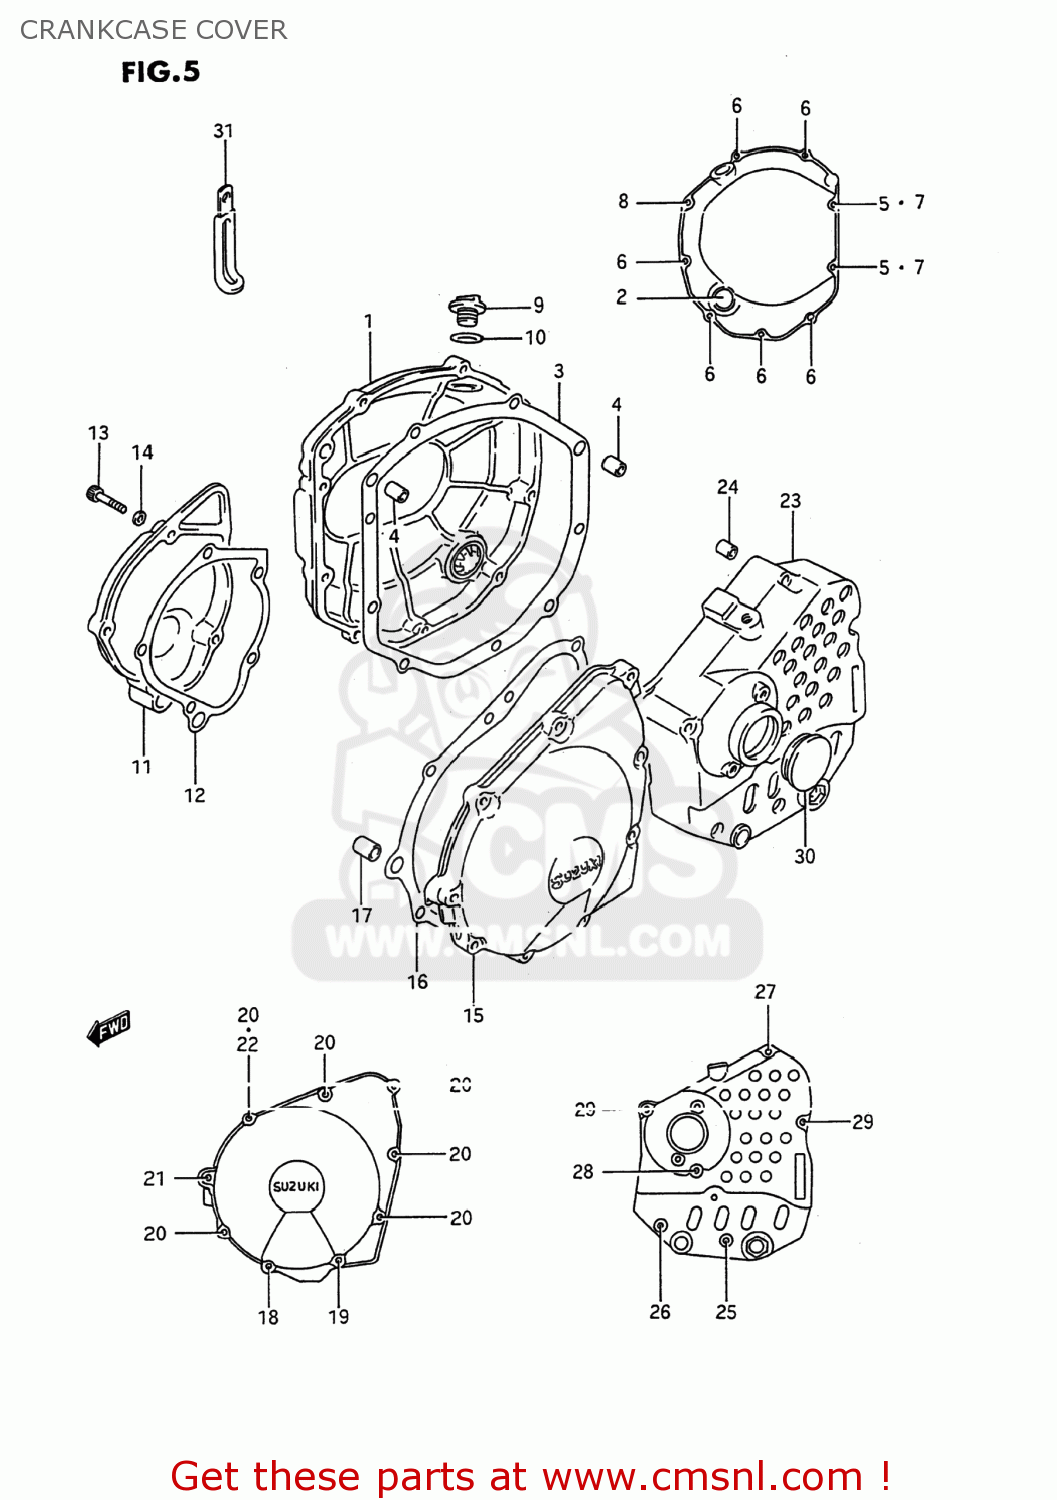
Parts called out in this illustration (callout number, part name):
1	COVER,CLUTCH
2	LENS,OIL LEVEL CHECK
3	GASKET,CL COVER (NAS)
4	PIN
5	GASKET(5.8X11X1.2) (NAS)
6	BOLT
7	BOLT
8	BOLT
9	PLUG
10	O RING(D:3.1,ID:16.8)
11	COVER,SIGNAL GENERATOR
12	GASKET,SIGNAL GENERATOR COVER (NAS)
13	BOLT
14	GASKET(5.8X11X1.2) (NAS)
15	COVER,STARTER GEAR
16	GASKET,STARTER GEAR COVER (NAS)
17	PIN (11X20)(SUS)
18	BOLT
19	BOLT
20	BOLT
21	BOLT
22	GASKET(5.8X11X1.2) (NAS)
23	COVER,ENGINE SPROCKET
24	PIN
25	BOLT
26	BOLT
27	BOLT
28	BOLT
29	BOLT
30	CAP(OD:36)
31	CLAMP
